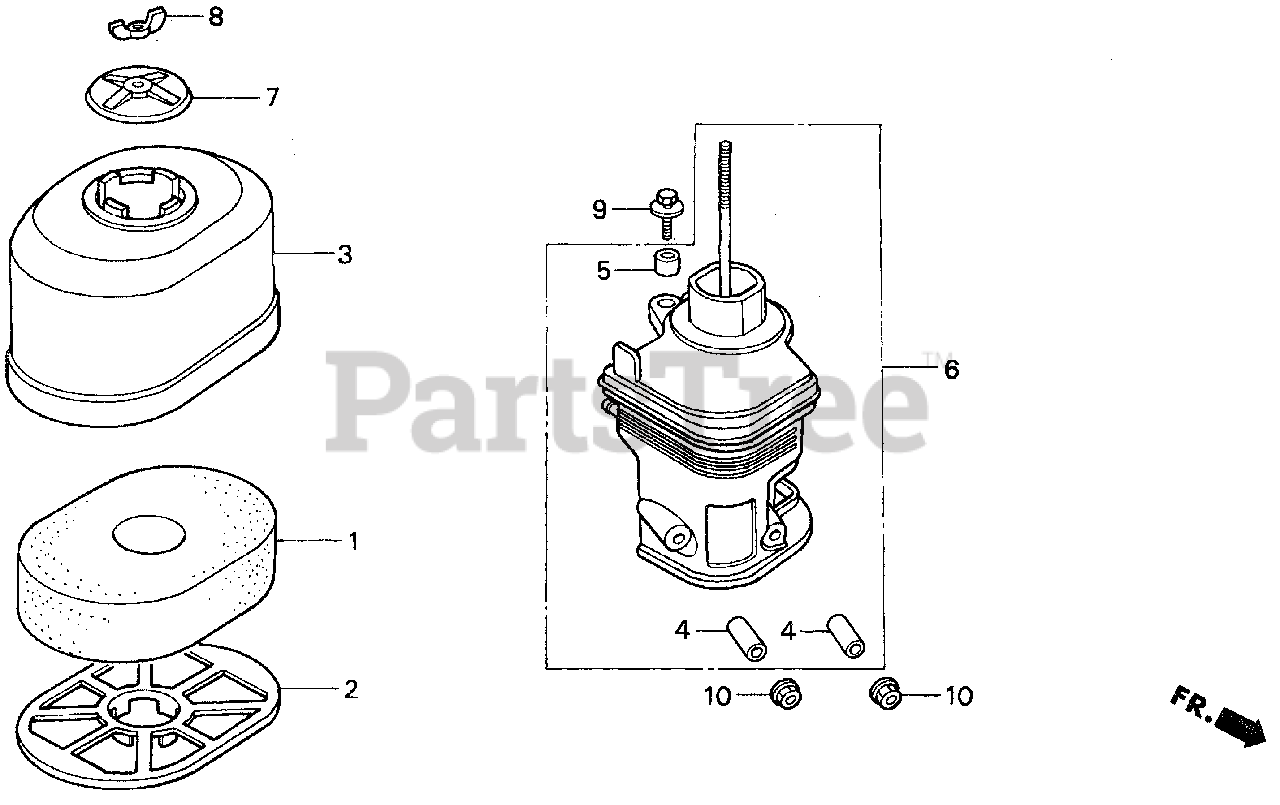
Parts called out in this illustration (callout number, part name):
1	ELEMENT, AIR CLEANER (SEMI DRY)
2	GRID, AIR CLEANER
3	COVER, AIR CLEANER (SEMI DRY)
4	COLLAR, AIR CLEANER
5	COLLAR B, AIR CLEANER
6	ELBOW, AIR CLEANER
7	CAP, AIR CLEANER
8	WINGNUT, TOOL BOX SETTING
9	BOLT-WASHER (6X22)
10	NUT, FLANGE (6MM)
